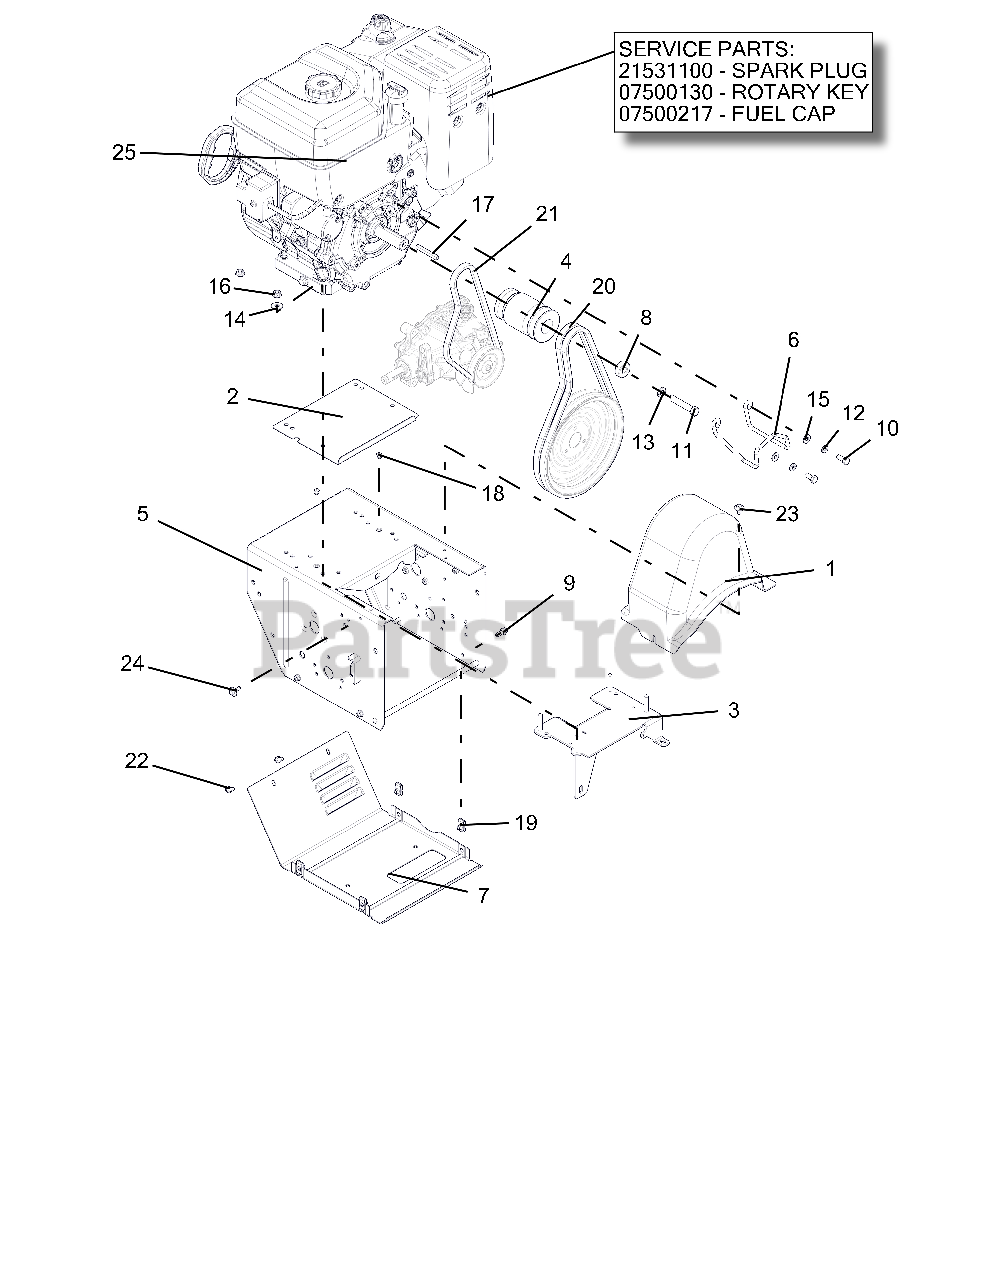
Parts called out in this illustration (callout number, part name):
1	COVER, BELT-LARGE PRO
2	BAFFLE,ENGINE-PRO SERIES
3	BRACKET, HYDROSTATIC TRANS XLG
4	SHEAVE, COMBO HYDRO WHEEL 4L
5	PRO HYDRO FRAME, MAIN
6	FINGER, BELT
7	COVER, BOTTOM - VENTILATED
8	BSHG-SPACER .47X1.25X.50
9	BLT-HEX .25-20X.75 HWH YZ GR5
10	BLT-HEX .31-24X.75 YWZC GR5
11	BLT-HEX .44-20X2.50 GR5 YWZC
12	WSHR-LK .312X.097 HVY YWZC
13	@WSHR-LK .44X.109 REG YWZC
14	@WSHR-FL-STL.38X.875X.083 YWZC
15	@WSHR-FL-STL.344X.688X.065YWZC
16	@NUT-LK-CTR-FLG .31-18 YZ GR F
17	KEY .25X.25X2.25
18	RVT-POP .187 YZ
19	NUT-RTNR .25-20X.56
20	V-BELT, HA-RAW EDGE (SET)
21	V-BELT, 4L-WRAPPED
22	SCR-TAP .25-20X.50 HWH TR YWZ
23	SCR-TAP .25-20X.50 LGHWH TR YZ
24	SCR-TAP .25-20X.5 CAPTIVE
25	ENGINE, BRIGGS PF 2100, 240V
25	PLUG, SPARK 20HP B&S VANGUARD
25	KEY, IGNITION ROTARY B&S
25	CAP, FUEL - BRIGGS & STRATTON
